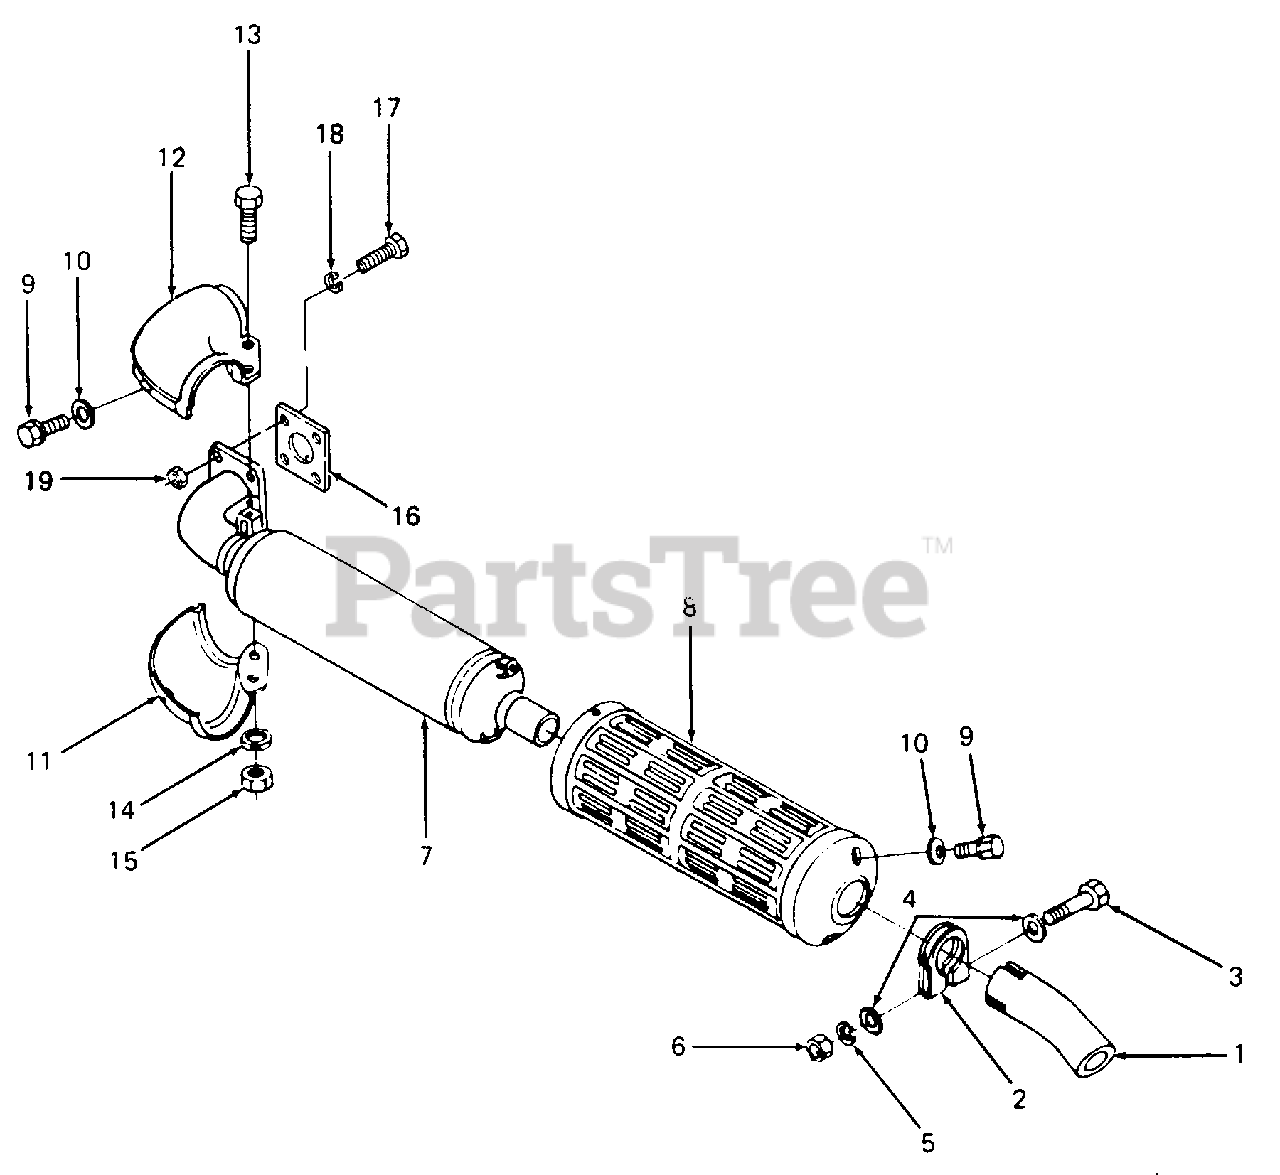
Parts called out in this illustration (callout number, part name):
1	Pipe, Muffler
3	Screw, Hex Cap
5	Washer, Spring
8	Cover, Muffler w/Graphic
9	Screw, Hex Cap
10	Washer, Flat
11	Cover, Muffler Flange
12	Cover w/Nut, Muffler Flange
13	Screw, Hex Cap
14	Washer, Spring
16	Gasket, Muffler
17	Screw, Hex Cap, 5/16-24 X 1.0 Lg GR5
18	Washer, Lock, 5/16
19	Nut, Hex, 5/16-24 GR5
